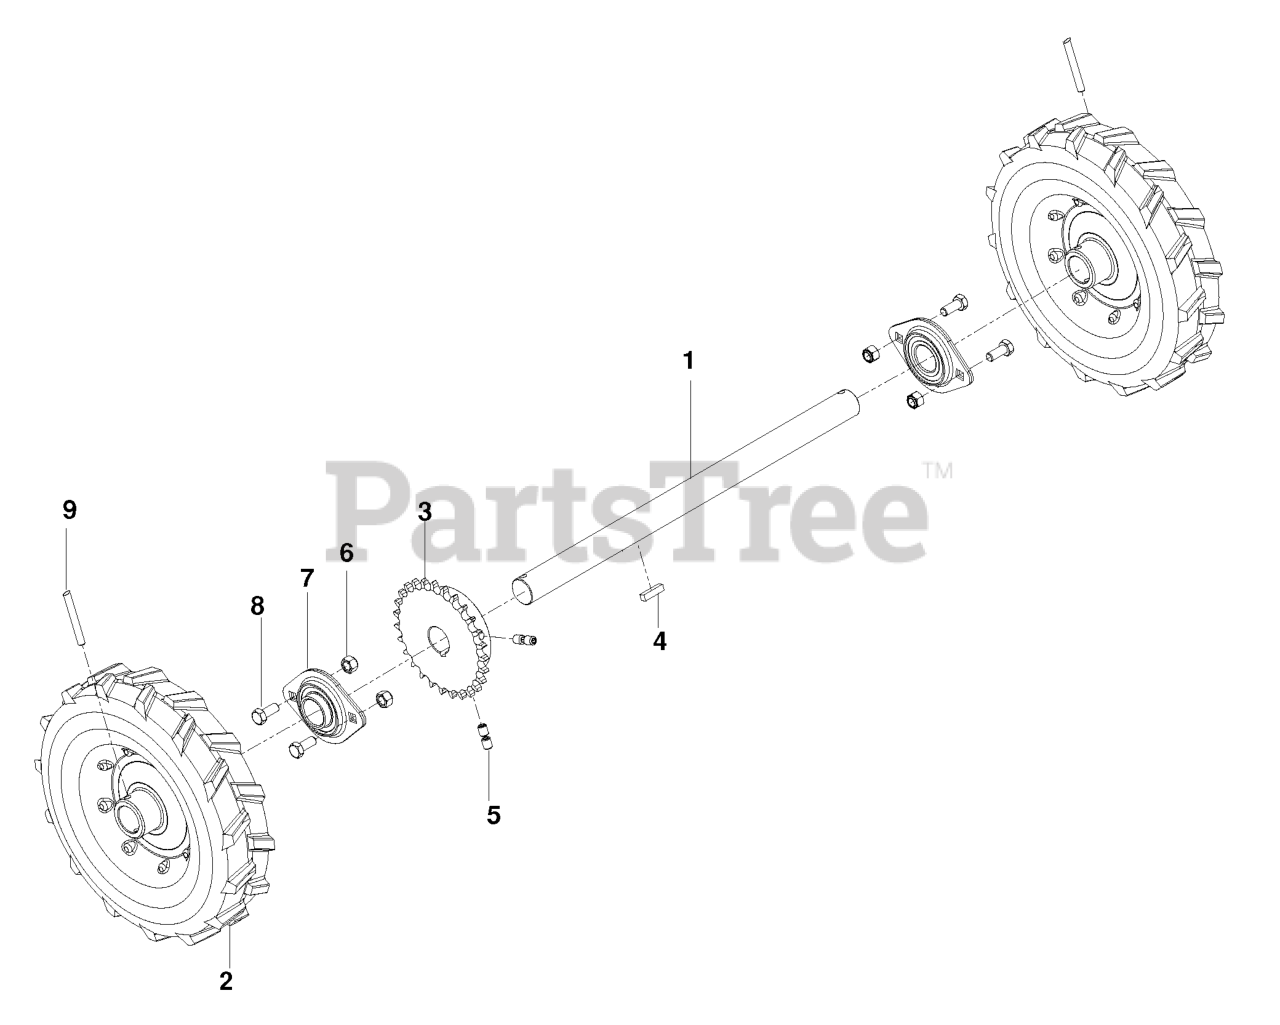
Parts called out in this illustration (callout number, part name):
1	AXLE SC18A
2	WHEEL, 2.75 X 10 X 1
3	SPROCKET W/KEY, ROTOR 27 TEETH
4	KEY 1/4 SQ X 1.0
5	SET SCREW 5/16 NYLOC
6	NUT 5/16 NYLOC
7	FLANGE BEARING ZINC PLATED 1"
8	HCS 5/16C X 3/4
9	SPIRAL PIN 1/4 X 1-1/2
